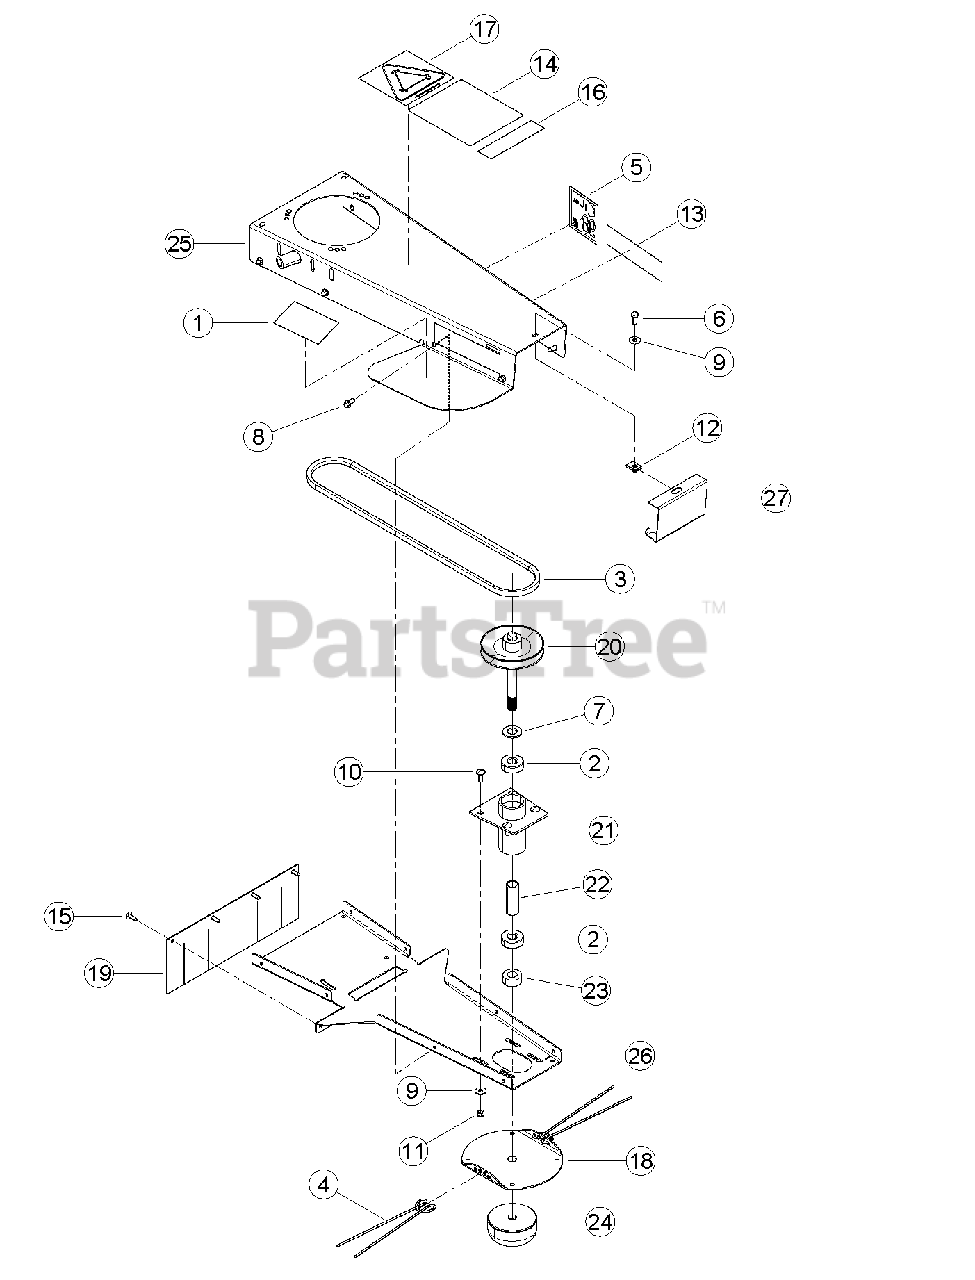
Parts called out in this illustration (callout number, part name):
1	DECAL, GRINDER DANGER
2	BEARING, 3/4 BALL
3	BELT, 4L 53 ARAMID
4	PLEASE SEE SERVICE PARTS & ACCESSORIES FOR REPLACEMENT OPTIONS
5	DECAL, 98 DB (WT160TXS MODEL)
6	BOLT, 5/16 X 3/4 HEX HD GR5 ZP
7	WASHER, 3/4 SAE FLAT ZP
8	SCREW, 11/32 X 7/8 HWH AB THREAD ZP
9	WASHER, 5/16 FLAT ZP
10	BOLT, 5/16 X 7/8 CRG GR5 NC ZP
11	NUT, 5/16 NE NYLOCK ZP
12	NUT, 5/16-18 TINNERMAN U-TYPE
13	DECAL, ECHO BEARCAT 6.82 X 1.90
14	DECAL, MANUAL/SAFETY INFO
15	RIVET, PLASTIC 1/4 X 7/8
16	DECAL, MODEL WT160T
17	DECAL, RECLAIM IT
18	DISK, TRIMMER HEAD
19	FLAP, TRIMMER
20	WELDMENT, TRIMMER PULLEY
21	WELDMENT, SPINDLE HUB
22	SPACER, TRIMMER SPINDLE
23	SPACER, TRIMMER HEAD
24	WELDMENT, TRIMMER HEAD USE 72704-12
25	WELDMENT, TRIMMER BODY
26	BOTTOM, TRIMMER FRAME
27	COVER, FRONT TRIMMER
